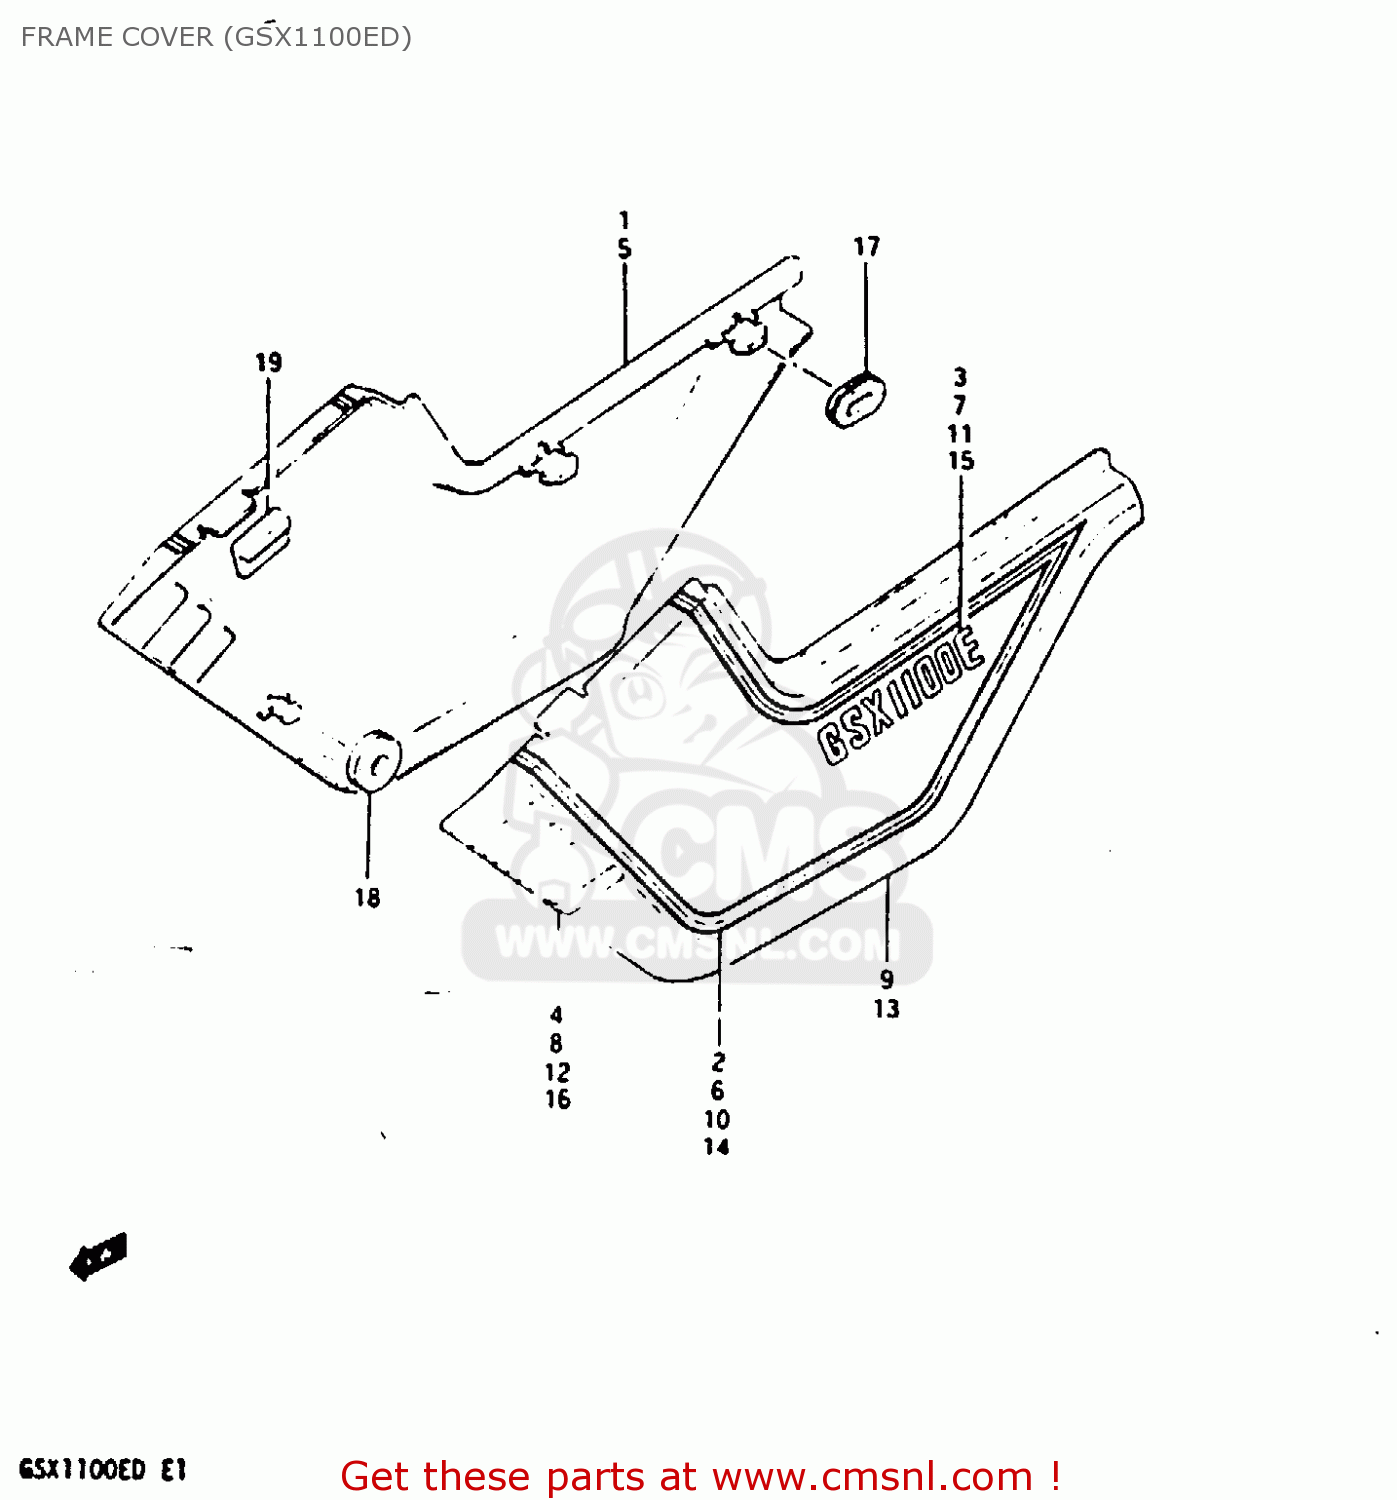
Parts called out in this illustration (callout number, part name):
1	COVER, FRAME RH
2	TAPE SET, FRAME COVER RH
3	EMBLEM, LH
4	LABEL, DENT
5	COVER, FRAME RH
6	TAPE SET, FRAME COVER RH
7	EMBLEM, LH
8	LABEL, DENT
9	COVER, FRAME LH
10	TAPE SET, FRAME COVER LH
11	EMBLEM, LH
12	EMBLEM,FRAME COVER,CENTER
13	COVER, FRAME LH
14	TAPE SET, FRAME COVER LH
15	EMBLEM, LH
16	EMBLEM,FRAME COVER,CENTER
17	CUSHION
18	CUSHION
19	CUSHION,FRAME COVER
